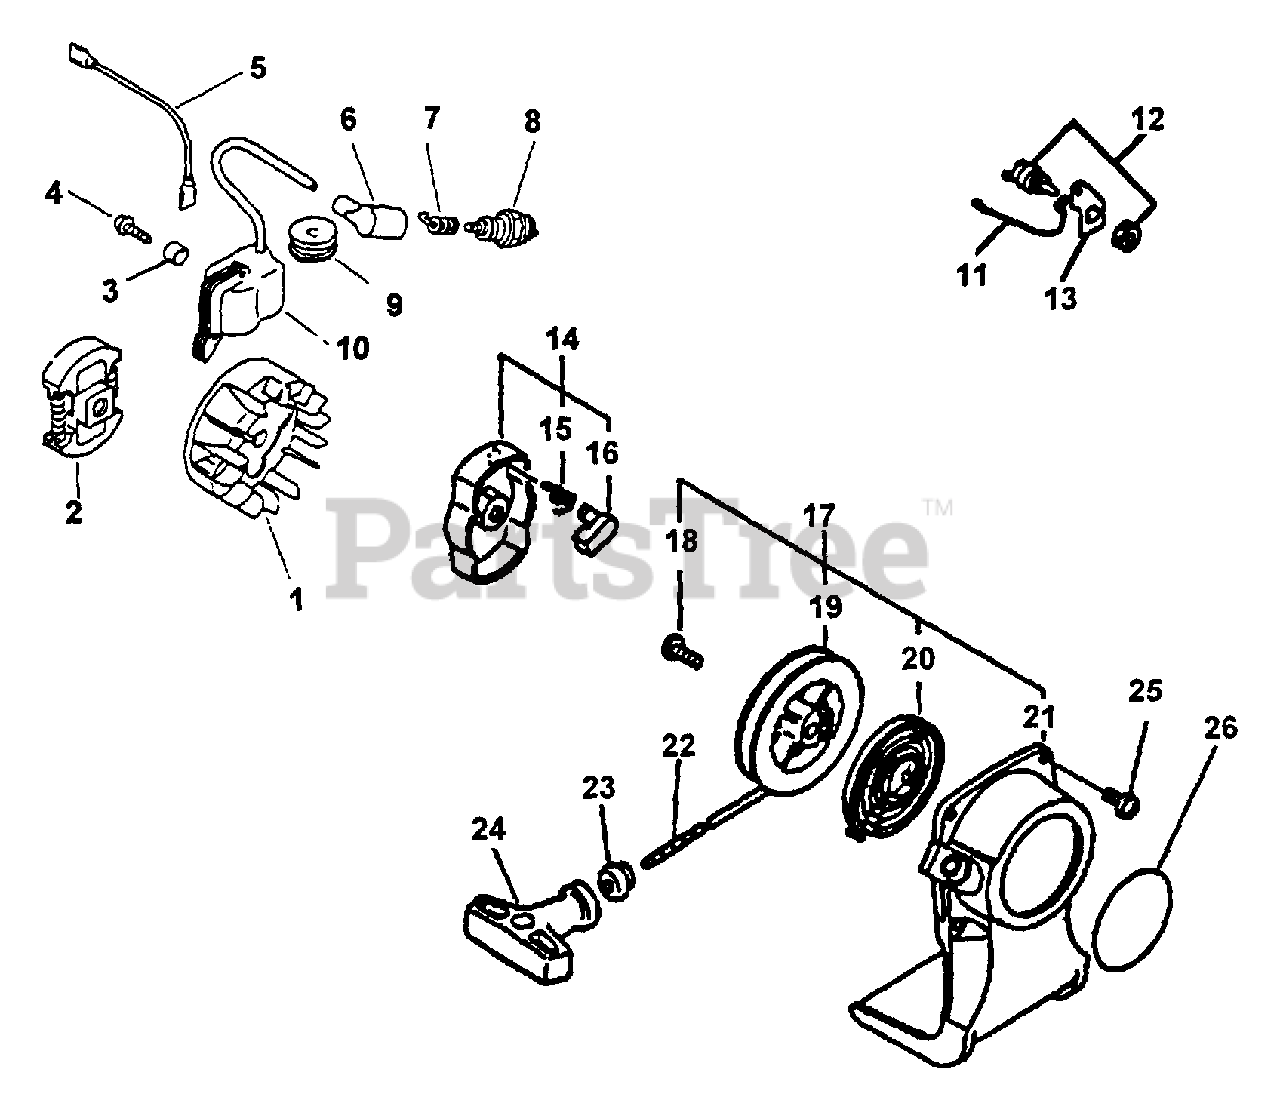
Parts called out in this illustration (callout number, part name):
1	FLYWHEEL
2	CLUTCH ASSY
4	SCREW - 4X22
5	LEAD - GROUND
6	CAP, SPARK PLUG
7	TERMINAL, SPARK PLUG CAP
8	SPARK PLUG -- BPM-7A
9	GROMMET
10	COIL, IGNITION
11	LEAD - GROUND
12	IGNITION SWITCH ASSY
13	BRACKET, SWITCH
14	STARTER PAWL ASSY
15	SPRING, RETURN
16	PAWL, STARTER - BLACK
17	STARTER ASSY
19	REEL, ROPE
20	SPRING, REWIND
21	CASE, STARTER - BLUE
22	ROPE, STARTER
23	GUIDE, ROPE
24	GRIP, STARTER
25	SCREW - 4X16
26	LABEL - ECHO
